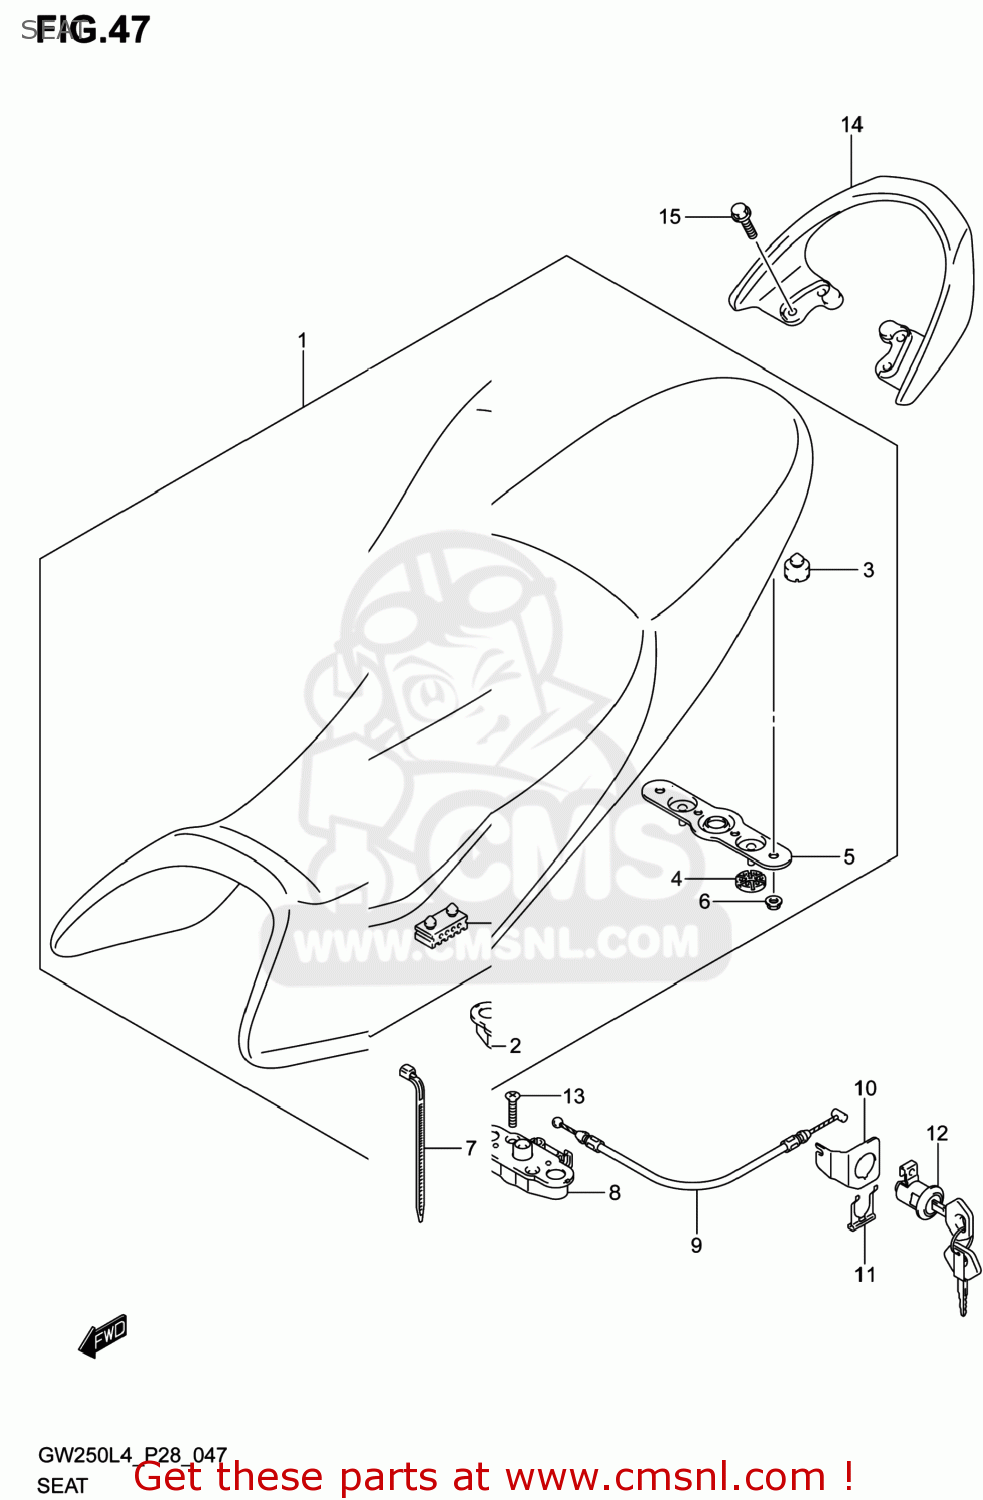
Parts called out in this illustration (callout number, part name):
1	SEAT ASSY
2	CUSHION,SEAT MOUNT
3	CUSHION,SEAT MOUNT
4	CUSHION,SEAT LOCK(10X22X6)
5	STRIKER,SEAT LOCK
6	NUT
7	CLAMP,WIRING HARNESS
8	BRACKET,SEAT SUPPORT
9	CABLE,SEAT LOCK
10	GUIDE,SEAT LOCK CABLE
11	PLATE,SEAT LOCK ASSY
12	LOCK SET,SEAT
13	SCREW
14	HANDLE,PILLION RIDER
15	BOLT
